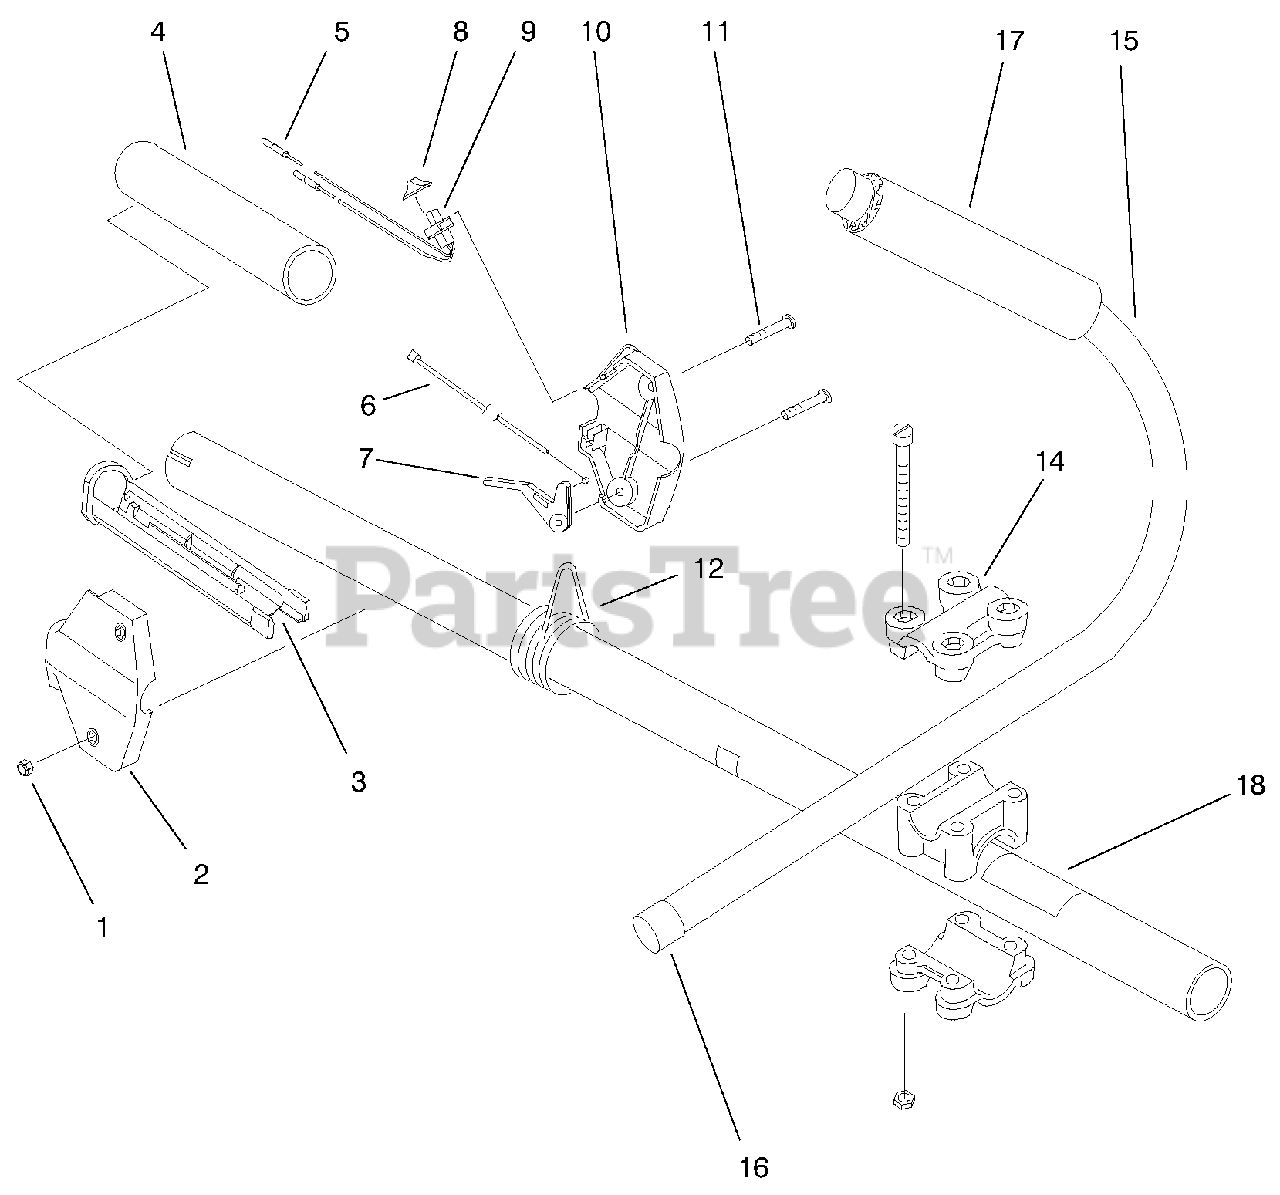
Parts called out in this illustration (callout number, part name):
1	Nut-Lock
2	R.H. Housing
5	Lead Wire Ass'y
6	Throttle Cable
7	Throttle Lever
8	Switch Cap
10	L.H. Housing
11	Hex Head Screw
12	Shoulder Strap Clamp
14	Handle Bracket Ass'y (Incl. 4 Screws & 4 Nuts)
15	J-Handle Assembly (Incl. Ref. #16-17)
16	Tube Closure
18	Decal-Safety Symbols
